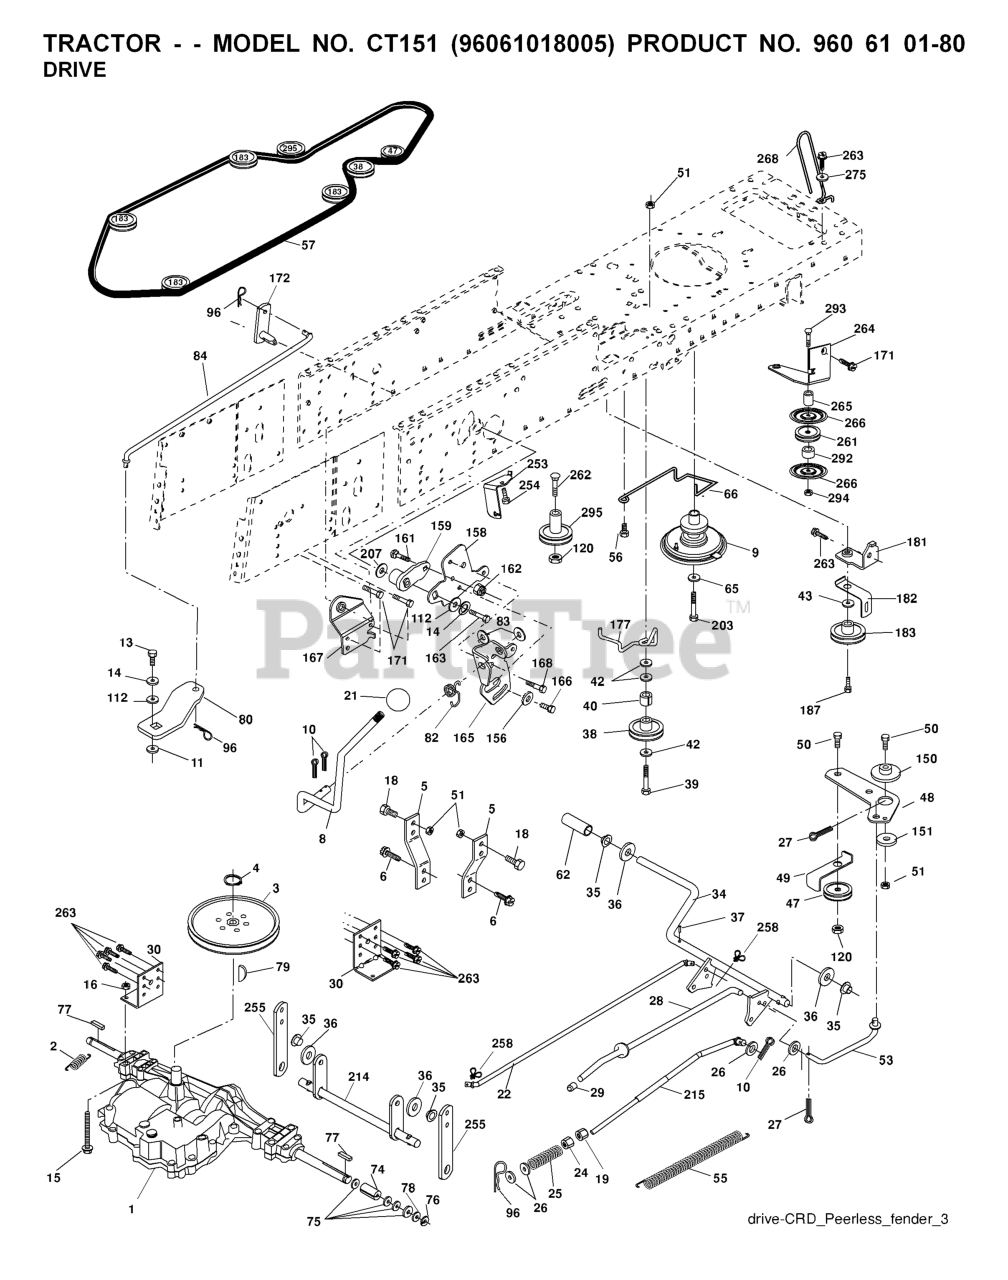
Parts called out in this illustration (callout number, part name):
2	SPRING,BRAKE RETURN
3	PULLEY
4	RETAINING RING LT
5	STRAP TORQUE
6	SCREW 5/16"
8	ROD SHIFT FENDER ADJUST LT
9	CLUTCH.ELECTRIC.OGURA.EURO.
10	PIN COTTER
11	WASH-SHFT PLT LT
13	BOLT 1/4-28X3/4
14	LOCKWASHER
15	BOLT HEX 5/16-18 GR 5
16	NUT.71038.31-18.HEX.NYLOCK
19	NUT
20	BOLT HEX 7/16-20X4-1/4"
21	KNOB.DUCKHEAD.1/2
22	ROD
24	NUT
25	SPRING ROD LT
26	WASHER
27	COTTER PIN
28	ROD, PARKING BRAKE
29	CAP
30	BRKT, MOUNT TRNSAXLE
34	SHAFT, FOOT PEDAL
35	BEARING.NYLON
37	DRIVE PIN
38	PULLEY.FLAT
42	WASHER
47	IDLER PULLEY
48	BELLCRANK, CLUTCH
49	RETAIN BELT
50	BOLT.3/8-16X1.50
53	LINK.CLUTCH.7.66.2005
55	SPRING, RETURN LT
56	SCREW.3/8-16
62	PEDAL COVER T
63	PULLEY.ENGINE.CVX.LT
65	LOCKWASHER
66	KEEPER BELT ENGINE
77	SQUARE KEY
79	KEY STD (1373) DANA
82	SHIFT SPRING
83	WASHER
84	LINK.T/A.CRD.D6800.18"CLR
96	RETAINER M
120	NUT LOCK FLG 3/8-16 UNC
150	BUSHING.BELLCRANK.GRD.DR
151	WASHER 12/32X2X10GA
156	WASHER.SRRTD.5/16
158	BRACKET
159	RB HUB.SHIFT
161	BOLT
162	NUT.CROWNLOCK.1/4
165	RP BRACKET
166	CAPSCREW.HXHD.FLG.5/16-18X.625
167	BRACKET.SUPT.SHIFT.CRD
168	BOLT.SHOULDER.5/16-18X
172	SHAFT
181	BRACKET
182	BELT GUIDE
183	PULLEY.V-IDLER.GRND.DR
187	BOLT.5/16-18X1.25
207	WASHER NYL
214	LEVER
243	BRACKET, ANTI-ROTATION
254	SCREW 3/8-16X1
255	SHAFT
258	CLIP RETAINER
261	FLAT IDLER PULLEY
263	SCREW, 3/8-16X3/4
266	PROTECTOR
268	GUARD MUFFLER
275	WASHER
292	SPACER
295	PULLEY IDLER COMPOSITE
